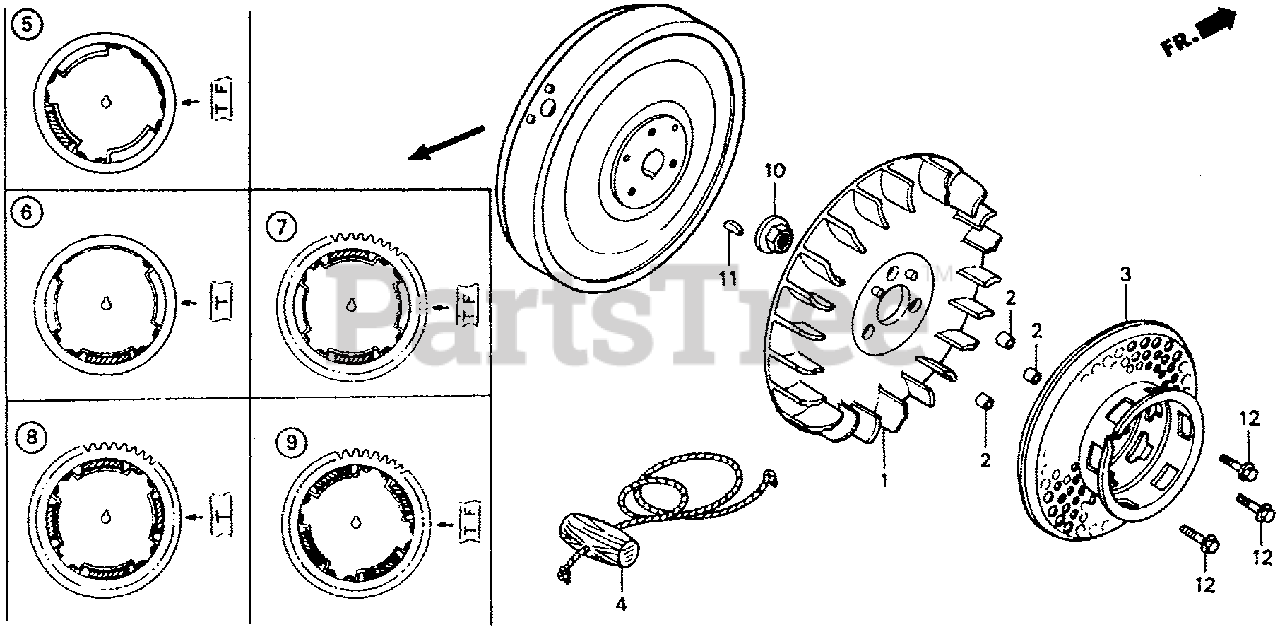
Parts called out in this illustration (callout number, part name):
1	FAN, COOLING
2	COLLAR, FAN
3	PULLEY, STARTER
4	ROPE, STARTER (#5X55")
5	FLYWHEEL
7	FLYWHEEL (STARTER)
8	FLYWHEEL (C.D.I. + STARTER)
9	FLYWHEEL (STARTER+RECTIFIER)
10	NUT, SPECIAL (16MM)
11	KEY, SPECIAL WOODRUFF (25X18)
12	BOLT, FLANGE (6X16)
